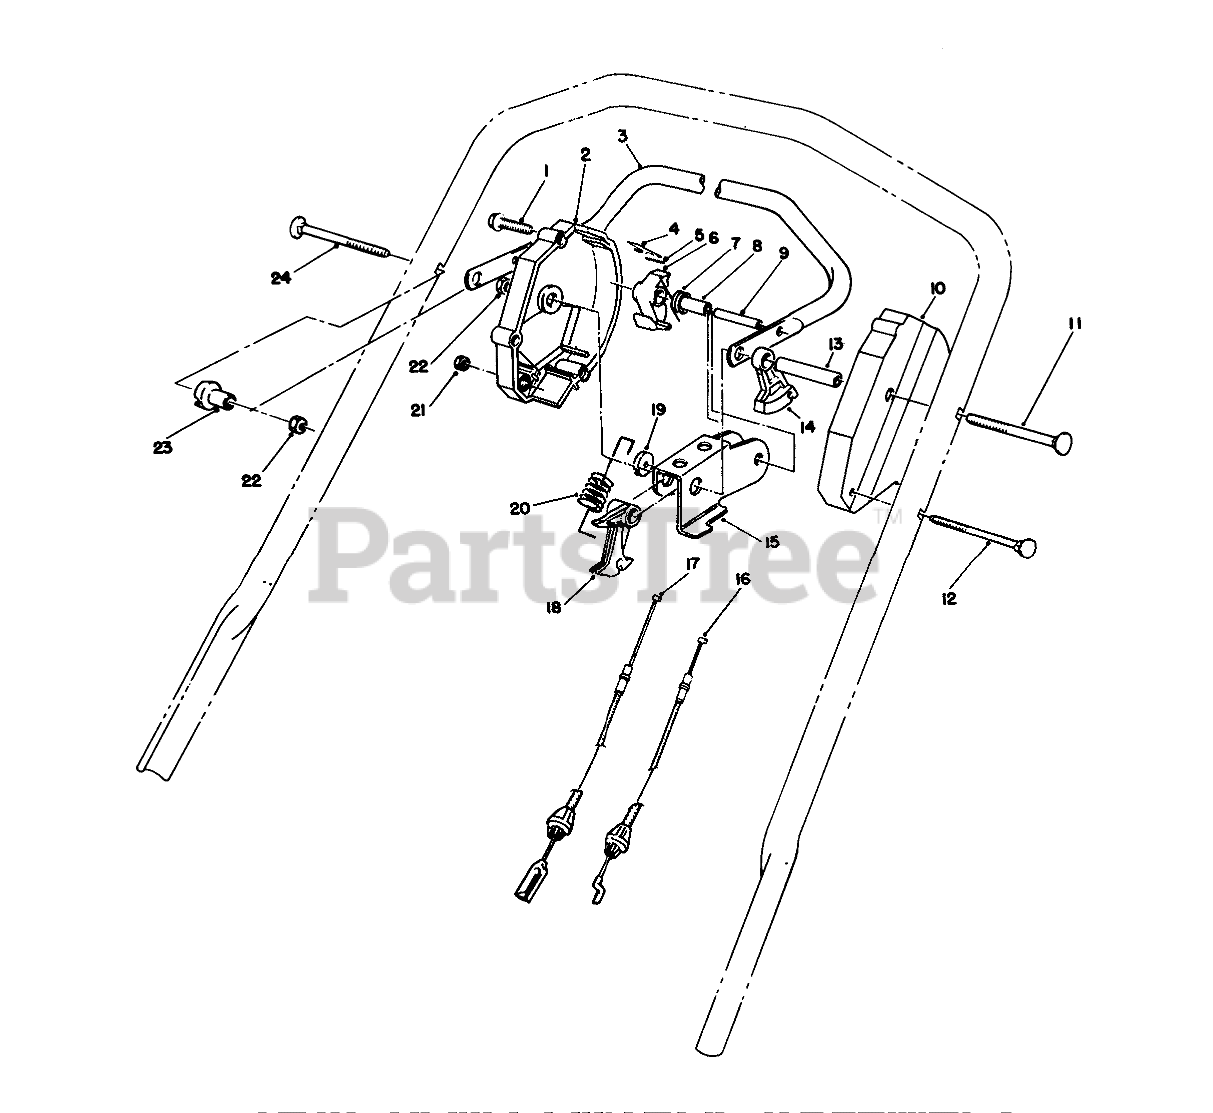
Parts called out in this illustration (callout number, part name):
1	SCREW-HWHTF
2	Housing-Control
3	Bar-Control
4	SPRING-LEAF
5	PIN-INSERT
6	HOOK-CONTROL
7	SPRING-TORSION
8	SPACER
9	PIN-ROLL, SLOTTED
10	HOUSING-CONTROL, LH
11	Screw-Handle
12	HANDLE SCREW
13	TUBING-SPACER
14	LEVER-TRACTION
15	ROCKER
16	Cable-Traction
17	Cable-BBC
18	LEVER-CABLE
19	WASHER-NYLON
20	SPRING-DETENT
21	NUT-HEX
22	NUT-LOCK, NI
23	SPACER-SUPPORT
24	SCREW-HANDLE
